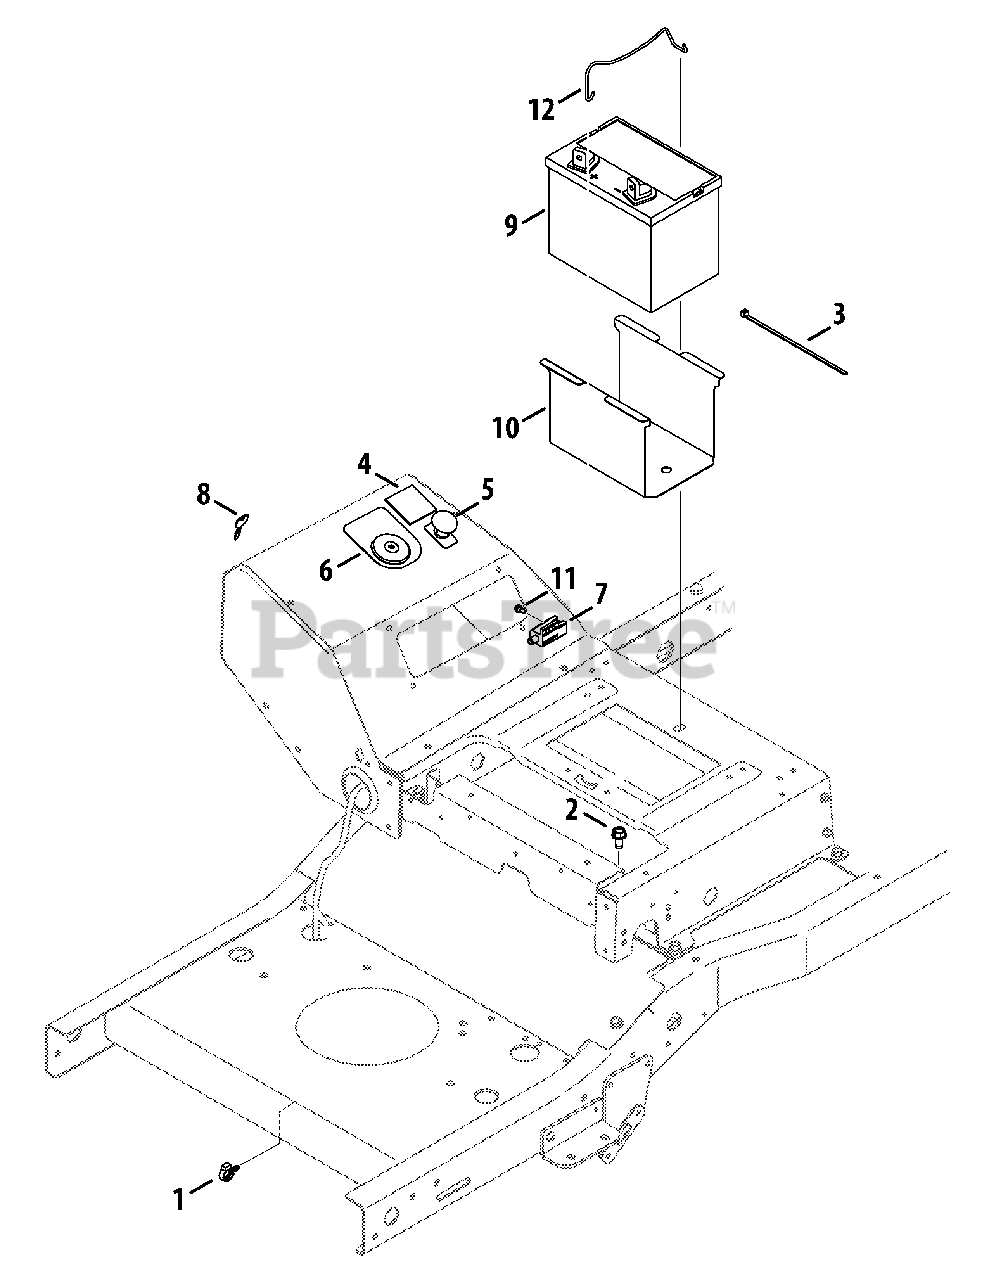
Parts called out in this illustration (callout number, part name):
1	Electrical Conduit Clip, 1/2
2	Screw, 3/8-16 x .75
3	Cable Tie, 3/16 x .05 x 7.4
4	Hour Meter/Service Minder
5	Electric PTO Switch
6	Key Switch
7	Interlock Switch
8	Universal Key
12	Battery Rod
